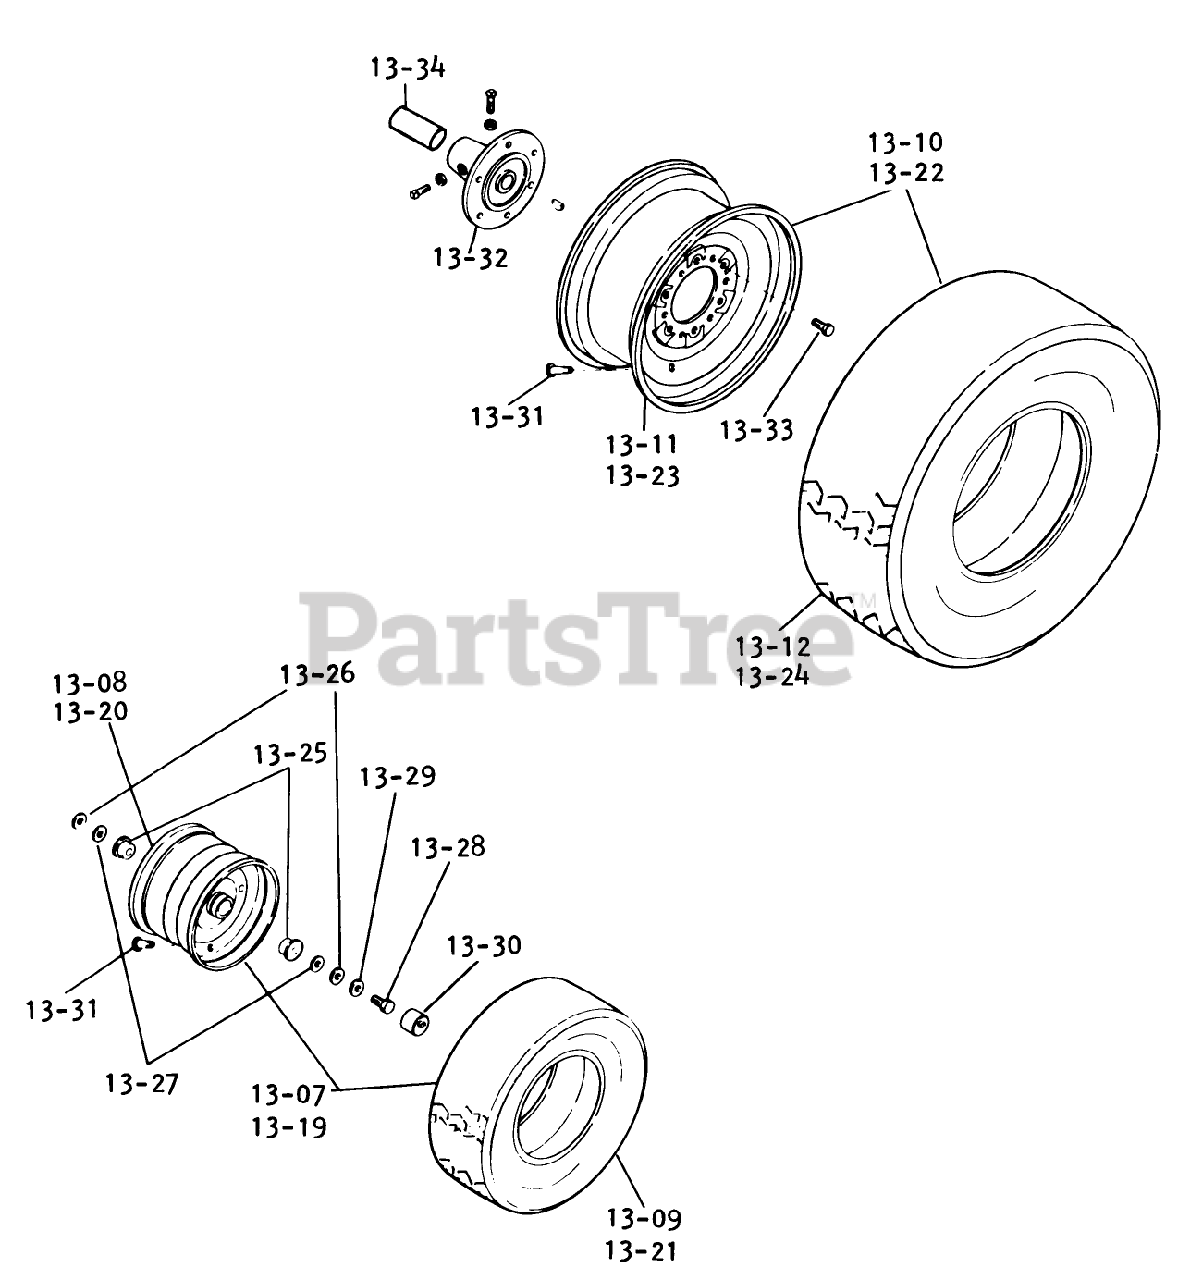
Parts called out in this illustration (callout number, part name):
13-07	ASSY-WHEEL
13-19	ASSY-WHEEL
13-22	Rear Wheel Tire Cleat
13-26	WASHER
13-29	WASHER
13-31	VALVE
13-33	BOLT-LUG, WHEEL
